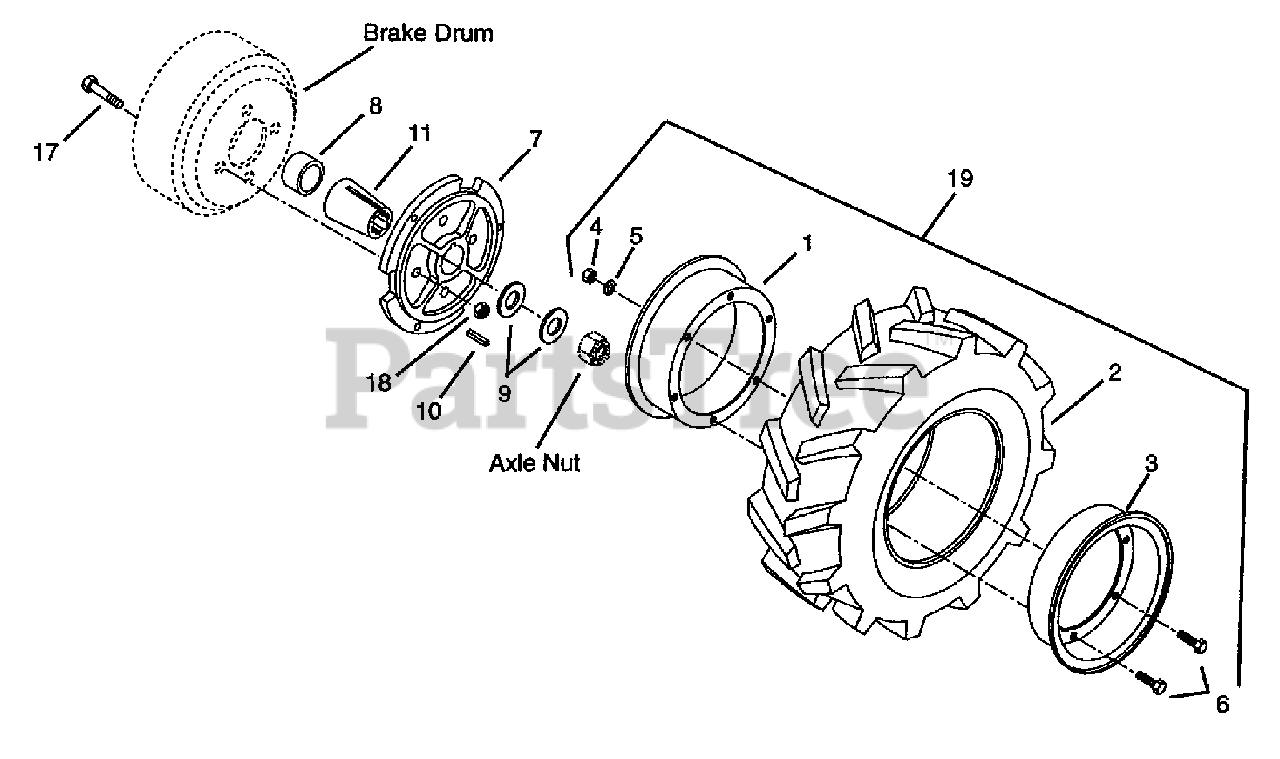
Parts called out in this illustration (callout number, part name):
1	Wheel 7.71 x 1.25 (104)
2	Tire 16 x 5W x 3 (104)
3	Wheel-Disc 6.75 x 9.219 (104)
4	Nut-Hex .38-16 (104)
5	Washer-Locking .375 x .094
6	Bolt-Hex .38-16 x .75 Grade 5
7	Hub-Wheel
8	Bushing-Sleeve 1.02 x 1.37 x 1.13
9	Washer-Flat-Steel .812 x 2.00 x .148
10	Key-Square .248 x 1.25 x .248
11	Insert-Hub
17	Bolt-Hex .50-13 x 1.25 (models with steering brakes only)
18	Nut-Lk-Ctr .50-13 (models with steering brakes only)
19	Tire and Wheel Assembly (104)
